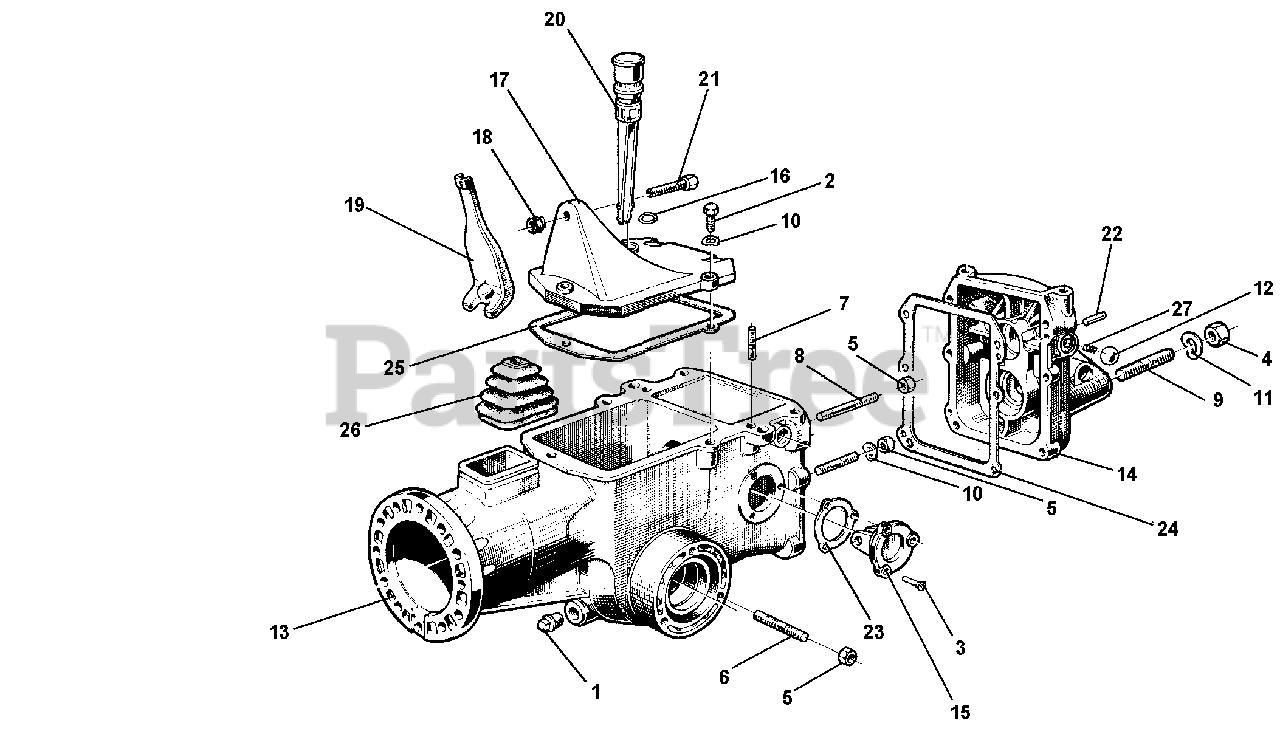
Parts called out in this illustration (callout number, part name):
1	PLUG 1/4 GAS
2	SCREW TE M8 X 25
3	SCREW TSV M6 X 16 UNI 260-5S
4	NUT M12 X 1.25 UNI 5587 6S
5	NUT, SELF LOCKING M8
6	STUD M8 X 46 X 20 X 12
7	STUD M8 X 38 X 14 X 20
8	STUD M8 X 58 X 16 X 16
9	ST.56XM12X1.25X26XM12X22 8G
10	WASHER, LOCK 8.4
11	WASHER, LOCK 13
12	BALL 15/32 RIV RB-11.906
13	HOUSING BODY
14	HOUSING COVER
15	FLANGE, REVERSE SPEED
16	RUBBER RING
18	STOP RING NUT
19	CLUTCH LEVER
20	CAP, WITH MEASURING ROD
21	SCREW, ADJUSTING M8
22	PARALLEL PIN D 6 X 20
24	GASKET, COVER
25	GASKET, COVER
